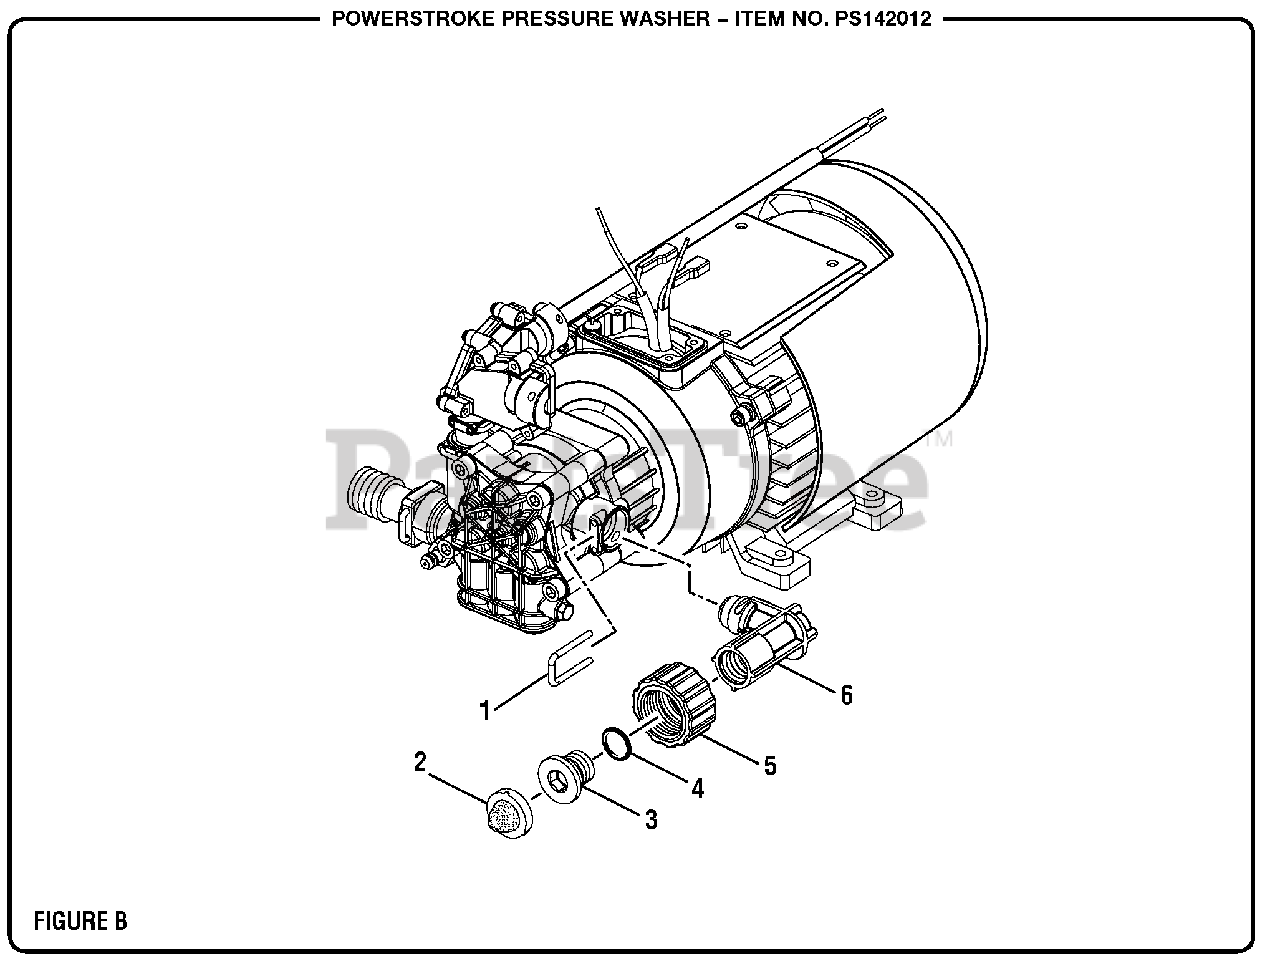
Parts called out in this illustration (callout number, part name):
2	Water Inlet Filter
3	Water Inlet Screw Nut
5	Water Inlet Connector
6	Inlet Tube
